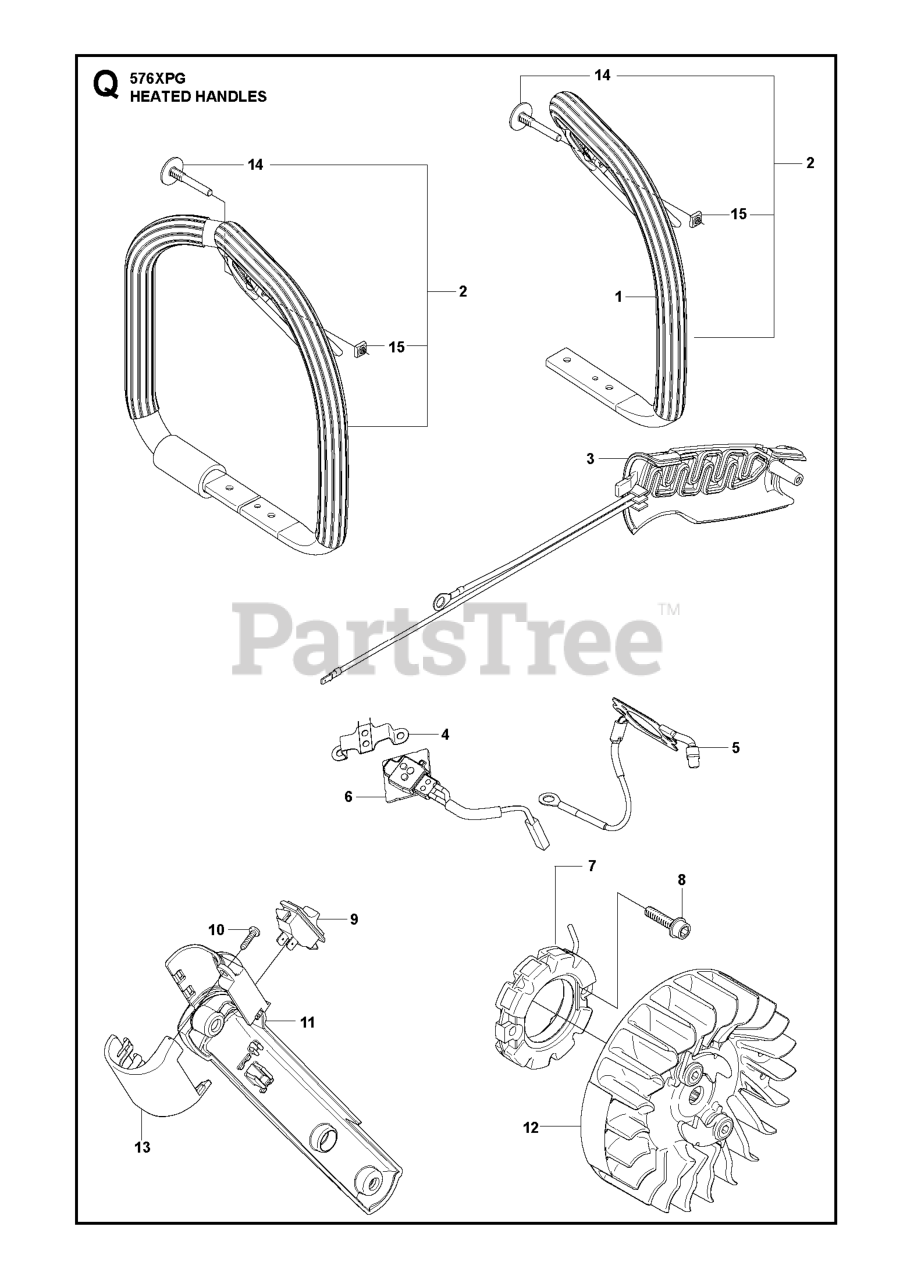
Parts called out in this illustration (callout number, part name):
1	HANDLE (G)
2	HANDLE (WAG)
5	HANDLE CIRCUIT
6	THERMOSTAT
